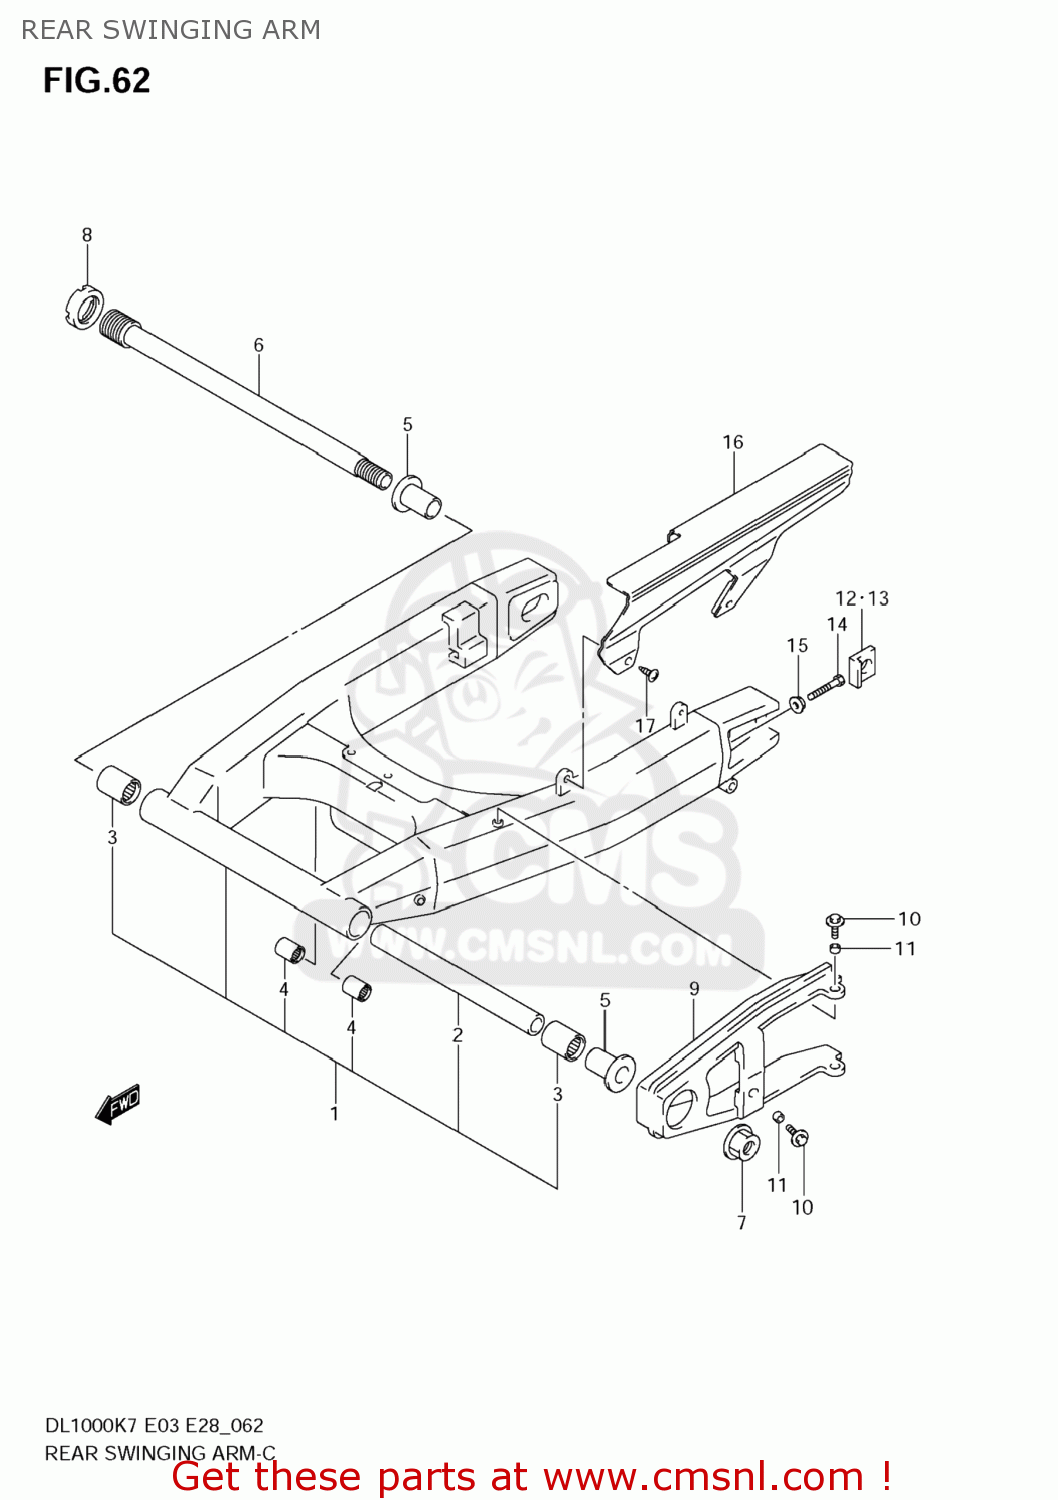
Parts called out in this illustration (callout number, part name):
1	SWINGING ARM ASSY, REAR
2	SPACER(20.8X27.2X196.7)
3	BEARING(25X33X35)
4	BEARING(17X24X25)
5	SPACER,RR SWGARM PIVOT BERRING
6	SHAFT,RR SWINGINGARM PIVOT
7	NUT,REAR SWING ARM PIVOT BOLT
8	NUT
9	BUFFER,CHAIN TOUCH DEFENSE
10	BOLT(6X20)
11	SPACER(6.5X9X5)
12	WASHER,CHAIN ADJUSTER
13	WASHER,CHAIN ADJUSTER
14	BOLT(8X50)
15	NUT
16	CASE,CHAIN
17	SCREW(6X16)
